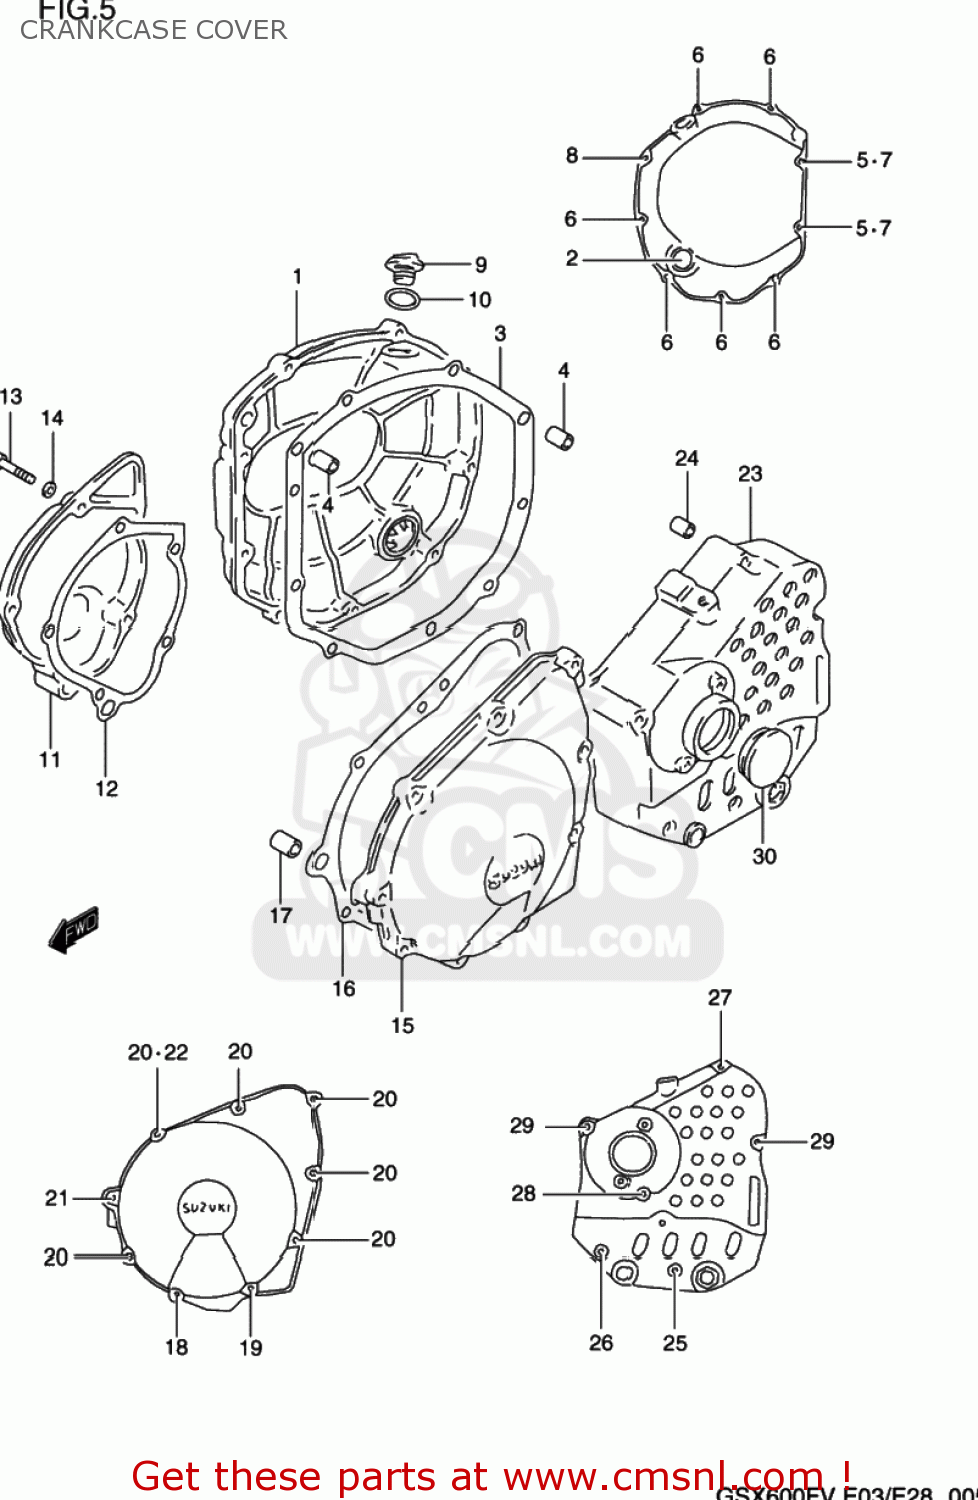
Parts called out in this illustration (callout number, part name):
1	COVER COMP,CLUTCH
2	LENS,OIL LEVEL CHECK
3	GASKET,CL COVER (NAS)
4	PIN
5	GASKET(5.8X11X1.2) (NAS)
6	BOLT,CL.COVER
7	BOLT
8	BOLT
9	PLUG
10	O RING(D:3.1,ID:16.8)
11	COVER,SIGNAL GENERATOR
12	GASKET,SIGNAL GEN COVER (NAS)
13	BOLT(6X22)
14	GASKET(5.8X11X1.2) (NAS)
15	COVER,STARTER GEAR
16	GASKET,STARTER GEAR COVER (NAS)
17	PIN(8.4X11X20)
18	BOLT,OIL FILLE
19	BOLT,CRKCASE,R
20	BOLT,CL.COVER
21	BOLT
22	GASKET(5.8X11X1.2) (NAS)
23	COVER,ENGINE SPROCKET
24	PIN
25	BOLT
26	BOLT
27	BOLT
28	BOLT
29	BOLT
30	CAP(OD:36)
